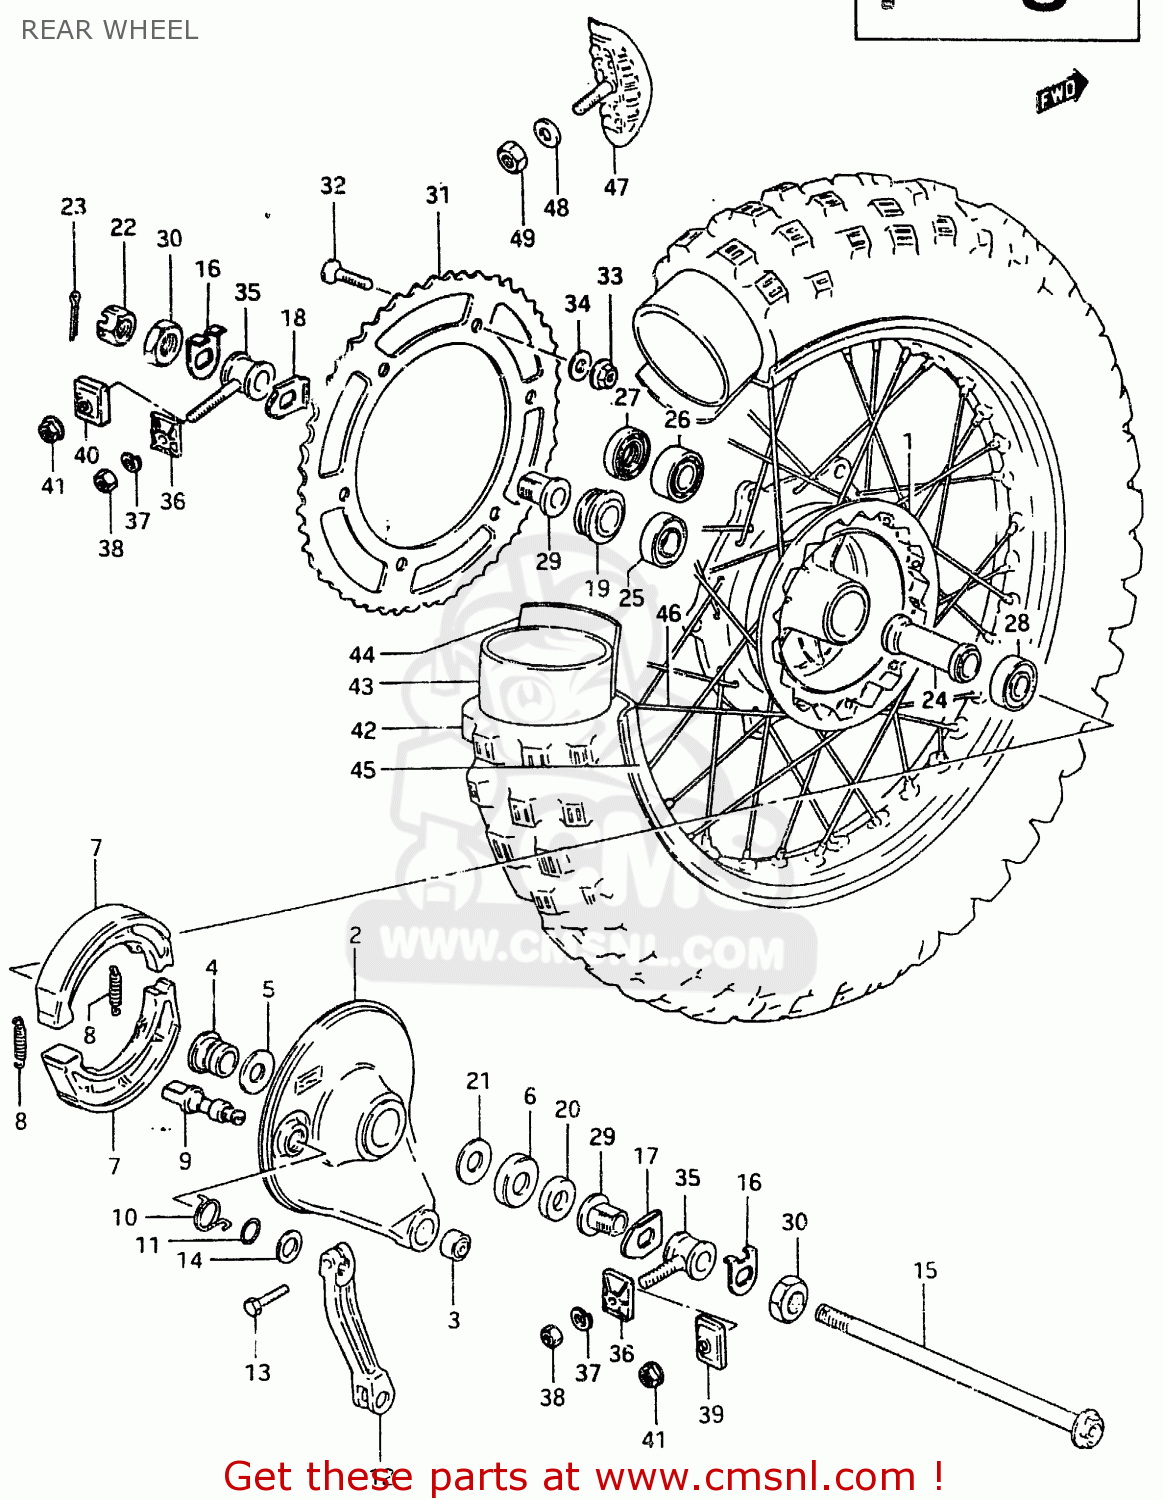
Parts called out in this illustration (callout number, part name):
1	DRUM,REAR HUB
2	PANEL SET,REAR HUB
3	SPHERICAL BRNG,TORQUE LINK
4	SPACER,RR BRAKE ANCHOR PANEL
5	SEAL,OIL(20X27X5)
6	CVR,RR BRAKE AHR PNL DUST SEAL
7	SHOE,BRAKE
8	SPRING
9	CAM,FR BRAKE
10	SPRING
11	O RING(D:2.5,ID:11.4)
12	LEVER,RR BRAKE CAM
13	BOLT
14	WASHER(12.5X20X1)
15	AXLE,REAR
16	WASHER,CHAIN ADJUSTER
17	PLATE,CHAIN ADJUSTER,RIGHT
18	PLATE,CHAIN ADJUSTER,LEFT
19	SPACER,RR AXLE,L
20	SPACER, AXLE RH
21	WASHER,THRUST
22	NUT
23	COTTER PIN
24	SPACER,REAR HUB BEARING
25	BEARING
26	BALL BEARING 15X35X16
27	OIL SEAL
28	BEARING
29	SPACER,CHAIN ADJUSTER
30	NUT
31	SPROCKET,REAR
32	SCREW
33	NUT
34	WASHER
35	ADJUSTER,CHAIN
36	PLATE,CHAIN ADJUSTER GEAR
37	LOCK WASHER
38	NUT
39	PLATE,CHAIN ADJUSTER GEAR
40	PLATE,CHAIN ADJUSTER GEAR
41	NUT
42	TIRE
43	TUBE,INNER
44	PROTECTOR,WHEEL,INNER
45	RIM,REAR WHEEL
46	SPOKE SET,REAR WHEEL
47	STOPPER,BEAD
48	WASHER
49	NUT
